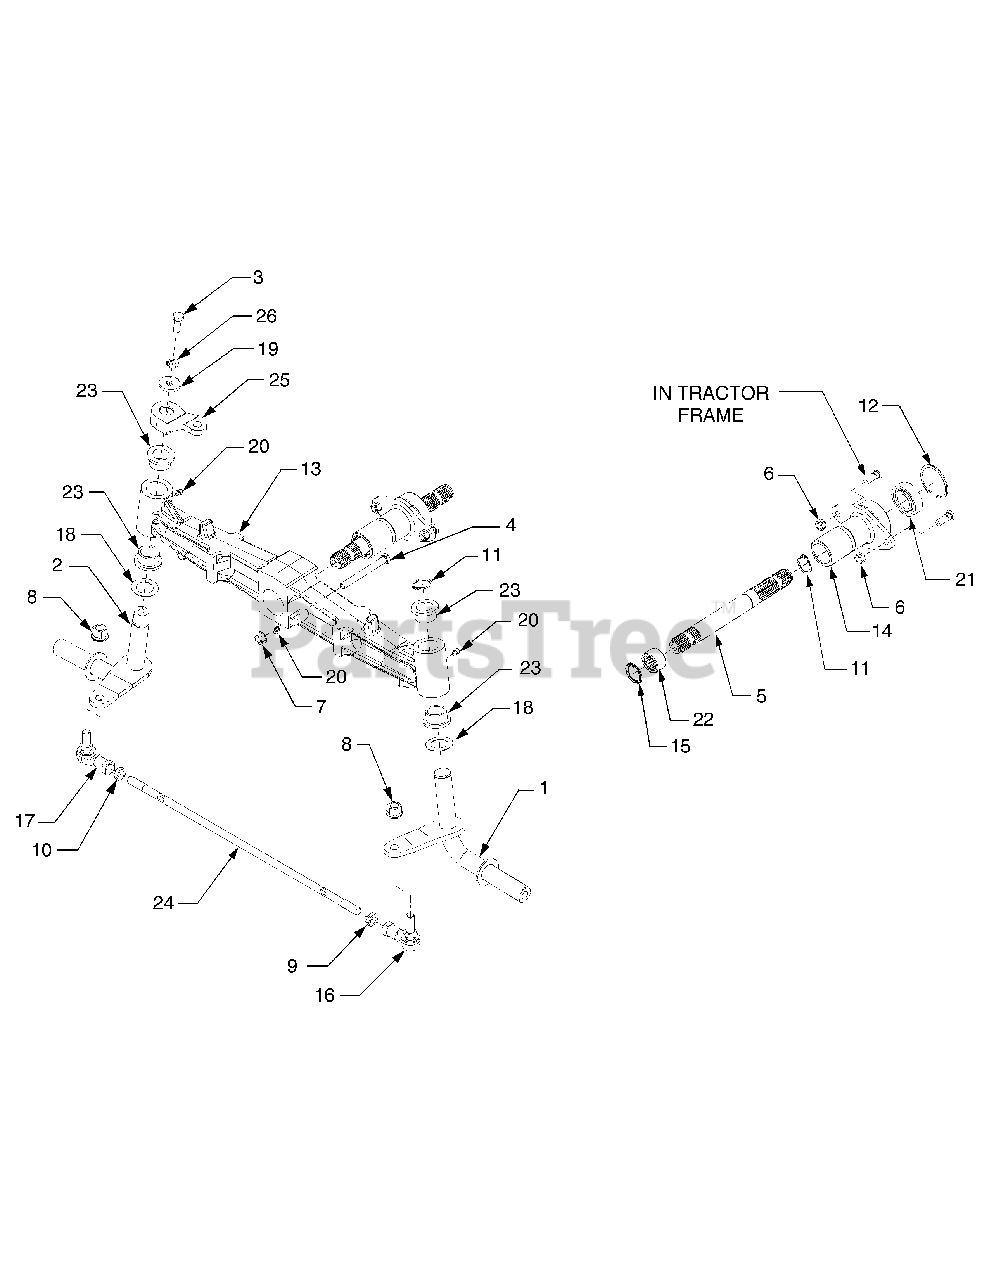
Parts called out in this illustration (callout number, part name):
4	Screw, Hex Cap 3/8-16 x 3.5 GR5
5	Shaft, Splined
6	Nut, Hex Center Lock, 3/8-24
7	Nut, Hex Flange Lock, 3/8-16
8	Nut, Hex Flange Lock, M12 x 1.75
9	Nut, Hex - RH, M12 x 1.75
10	Nut, Hex - LH, M12 x 1.75
11	Snap Ring, 1.0 Dia. Shaft
12	Retaining Ring, Internal, 2.0
13	Pivot Axle
14	Axle Carrier
15	Seal, Grease, 1.31 x 1.0
16	Ball Joint, 12MM x 1.75 RH
17	Ball Joint, 12MM x 1.75 LH
18	Washer, Flat, 1.03 x 1.62 x .030
19	Washer, Flat, .406 x 1.25
20	Fitting, Lube, 3/16 Drive
21	Bearing, Ball
22	Bearing, Needle
23	Bearing, Flange
24	Tie Rod, M12 x1.75 RH & LH
25	Steering Arm
26	Washer, Lock, 3/8
